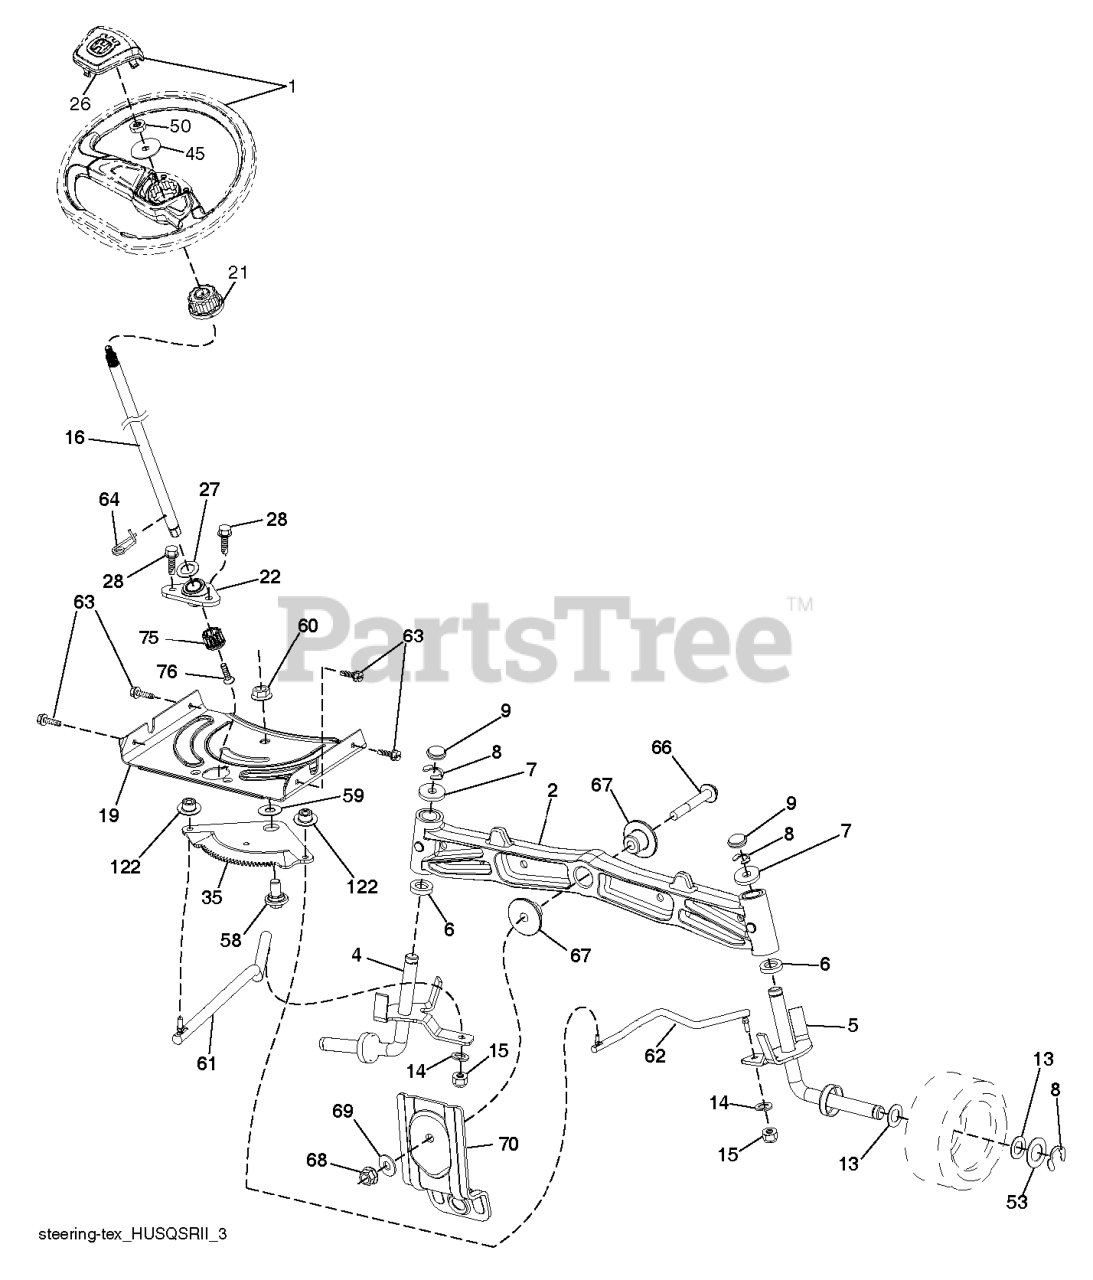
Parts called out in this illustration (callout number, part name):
1	Service Kit
2	AXLE.SVC.ASM CAST IRON.TEX
4	SPINDLE.WLDMT.LH.15INTIRE.X431
5	SPINDLE.WLDMT.RH.15INTIRE.X431
6	WASHER THRUST
9	CAP.SPINDLE.BLACK
15	NUT CROWNLOCK 3/8-24
16	KIT.SRVC.STEERINGSHAFT.2HISHFT
19	SERVICE KIT PLATE PLATE.STEER.
21	KIT.SRVC.STEERINGSHAFT.ADAPTER
22	KIT.SRVC.STEERINGSHAFT.LWRBSHG
28	SCREW, 3/8-16X3/4
35	GEAR.SECTOR.PLATE.DDL.
45	WASHER.3/8ID.2-3/8OD.12GA.PLTD
50	NUT.HEX.FLANGE.3/8-16.LOCKNUT
53	WASHER.HARDENED
58	BOLT.SHOULDER.SECTOR.P
59	WASHER.THURST.SECTOR.S
60	NUT.FLANGE.LOCK.5/8-11
61	Links
62	Links
63	BOLT.HEX.HD.WASHER.5/16-18X.75
64	RETAINER.CLIP.SPRING.S
66	BOLT HEX FGHD 7/16-14 X 3 SERR
68	NUT.LOCK.FLANGE.7/16
69	WASHER.1.5X.505X.118
70	BRACKET FRONT DECK SUSPENSION
75	KIT.SRVC.STEERINGSHAFT.PINION
76	SCREW HEAD SOCKET LRVB
122	CAP.GEAR.SECTOR.TEX
